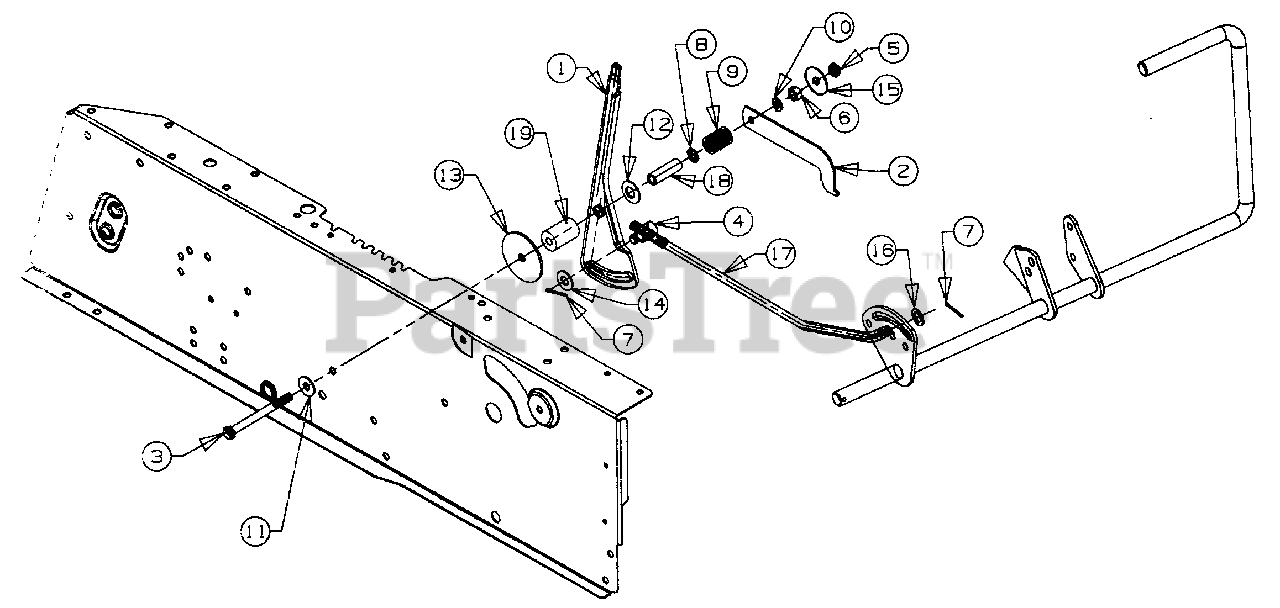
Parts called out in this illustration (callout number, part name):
1	Speed Selector Lever
2	Shift Lever Support
3	Hex Bolt 5/16-18 x 3.5" Lg.
4	Ferrule 3/8-24 Thd.
5	Hex Jam Nut 5/16-18 Thd.
6	Hex Nut 5/16-18 Thd. (Gr. 5)
7	Cotter Pin 3/32" Dia. x 1"
8	Speed Nut 5/16-18 Thd.
9	Compression Spring
10	L-Wash. 5/16" I.D.
11	FL-Wash. .345" I.D. x .88"
12	Bell-Wash. .505" I.D. x 1"
13	FL-Wash. .34" I.D. x 2.25"
14	FL-Wash. .385" I.D. x .87"
15	FL-Wash. .32" I.D. x 1.25" O.D.
16	FL-Wash. .469" I.D. x .75"
17	Speed Control Rod
18	Spacer 1.56" Lg.
19	Spacer 1.46" Lg.
